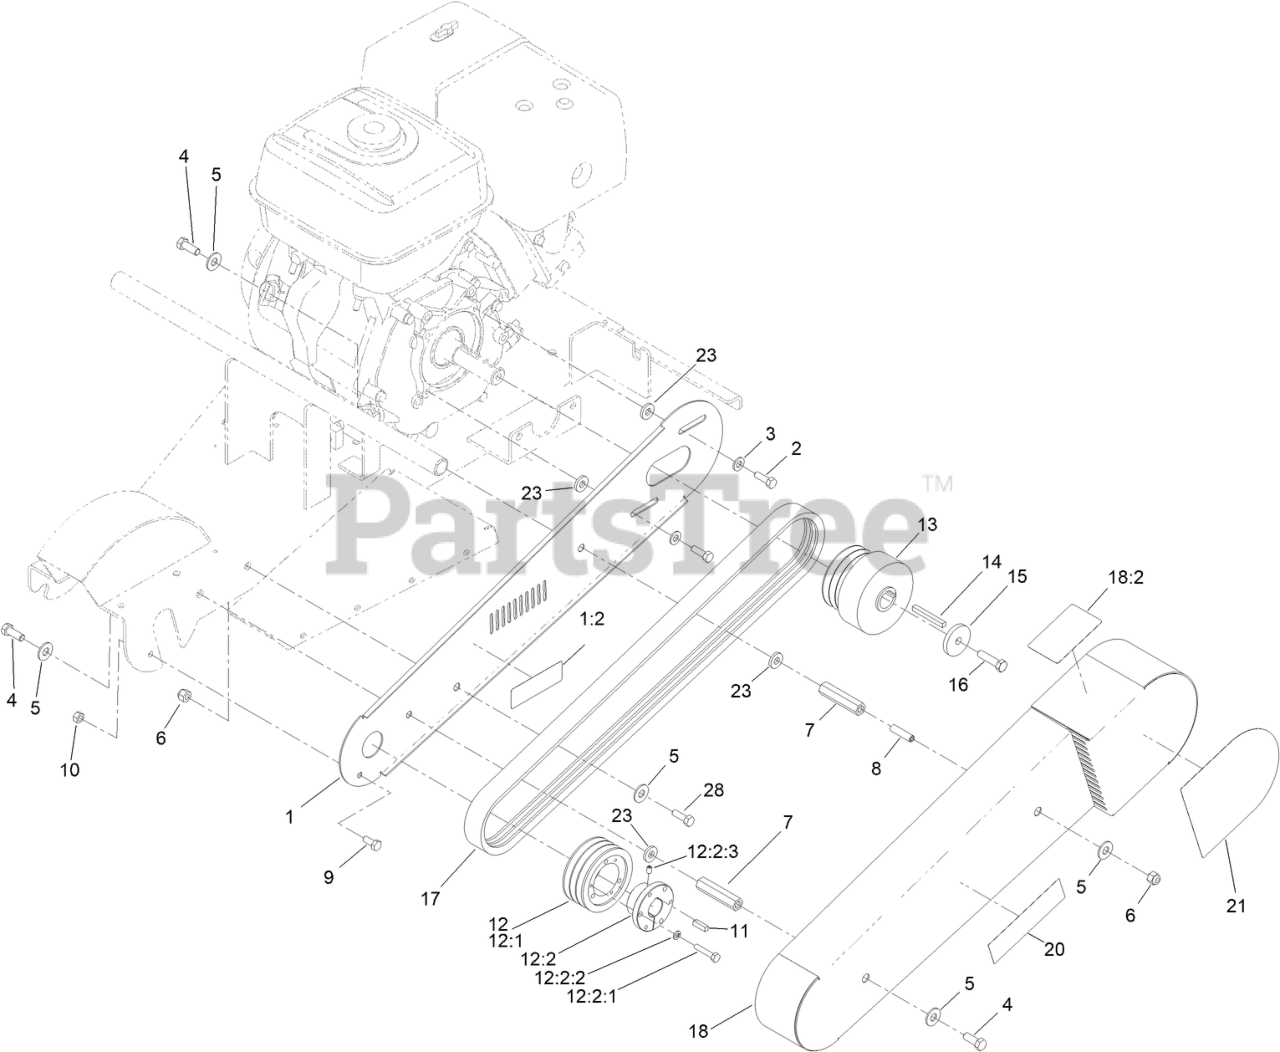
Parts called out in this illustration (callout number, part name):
1	PLATE-GUARD
1:2	DECAL-WARNING
2	SCREW-HH, PATCH
3	WASHER-FLAT
4	SCREW-HH
5	WASHER-FLAT
6	NUT-LOCK, NI
7	SPACER-GUARD
8	SCREW-SET, HSH
9	SCREW-HH
10	NUT-HEX
11	KEY-SQUARE
12	SHEAVE ASM
12:1	PULLEY
12:2	BUSHING
12:2:1	SCREW-HH
12:2:2	WASHER-LOCK
12:2:3	SCREW-SET, HSH
13	CLUTCH
14	KEY-SQUARE
15	WASHER-PLAIN
16	SCREW-HH
17	BELT-3V
18	BELT GUARD ASM
18:2	DECAL-CAUTION
23	SPACER
28	SCREW-HH
